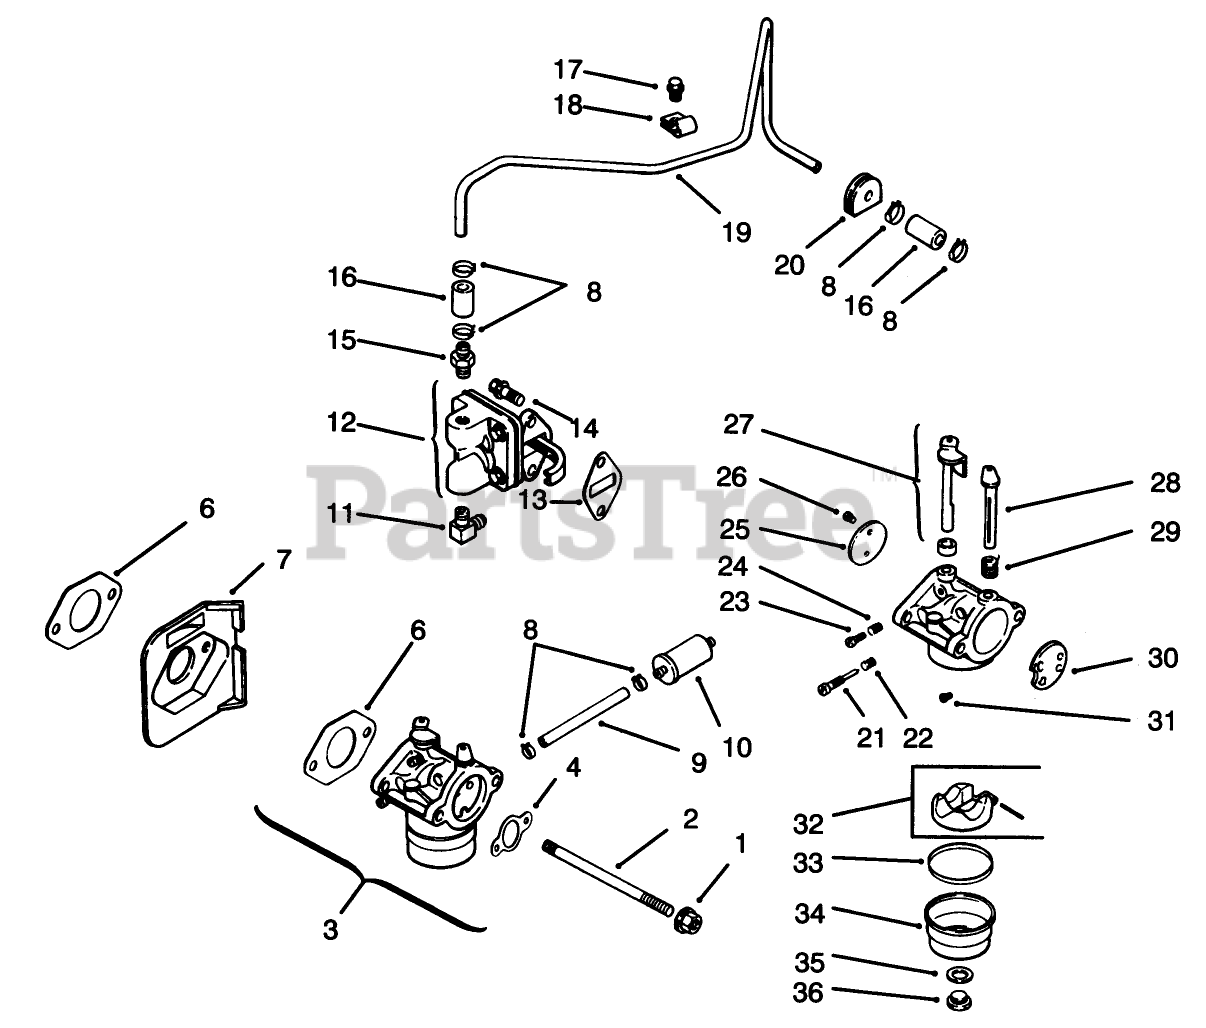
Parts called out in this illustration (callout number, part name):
2	Stud M6x1.0x110 (Only On: 72042,72043,72062,72063)
3	Kit-Carb INCL 4/6/21 -36 (Only On: 72042,72043,72062,72063)
4	Gasket-Air Cleaner (Only On: 72042, 72043, 72062, 72063)
6	Gasket-Carburetor (Only On: 72042, 72063, 72062, 72043)
7	Deflector-Heat (Only On: 72042,72043,72062,72063)
8	Clamp
9	Line-Fuel 3" (Only On: 72042, 72063, 72062, 72043)
10	Filter-Fuel (Only On: 72042,72043,72062,72063)
11	Connector
12	Kit-Pump INCL 13-14 (Only On: 72042,72043,72062,72063)
13	Gasket-Fuel Pump (Only On: 72042,72043,72062,72063)
14	Screw
15	Connector
16	Line-Fuel 1.25 Inch (Only On: 72042,72043,72062,72063)
18	Clamp-Fuel Line (Only On: 72042, 72063, 72062, 72043)
19	Line-Fuel (Only On: 72042,72043,72062,72063)
20	Grommet (Only On: 72042, 72063, 72062, 72043)
21	Needle-Idle Fuel Adjust (Only On: 72042, 72063, 72062, 72043)
22	Spring-Idle Fuel (Only On: 72042, 72063, 72062, 72043)
23	Screw-Idle Speed Adjust (Only On: 72042,72043,72062,72063)
24	Spring-Idle Fuel (Only On: 72042, 72063, 72062, 72043)
25	Plate-Throttle (Only On: 72042,72043,72062,72063)
26	Screw-Throttle Plate (Only On: 72042,72043,72062,72063)
27	Shaft-W/Lever Seal (Only On: 72042, 72063, 72062, 72043)
28	Shaft-Choke (Only On: 72042. 72063, 72062, 72043)
29	Spring-Choke Return (Only On: 72042,72063, 72062, 72043)
30	Plate-Choke (Only On: 72042, 72063, 72062, 72043)
31	Jet-Main (Only On: 72042, 72063, 72062, 72043)
32	Kit-Float (Only On: 72042,72043,72062,72063)
33	Gasket-Bowl (Only On: 72042,72043,72062,72063)
34	Bowl-Fuel (Only On: 72042, 72063, 72062, 72043)
35	Gasket-Bowl Screw (Only On: 72042, 72063, 72062, 72043)
36	Screw-Fuel Bowl (Only On: 72042, 72063,72062, 72043)
